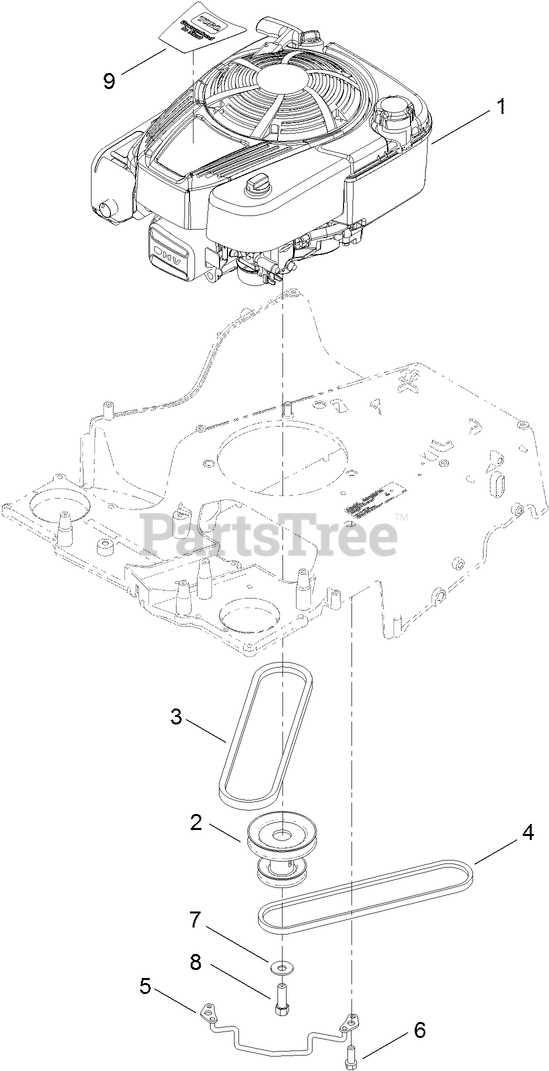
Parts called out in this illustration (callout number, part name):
2	PULLEY-ENGINE
3	V-BELT
4	V-BELT, TRACTION
6	SCREW-TAPTITE
7	WASHER-BELLEVILLE
8	SCREW-HH
9	DECAL-SHROUD
